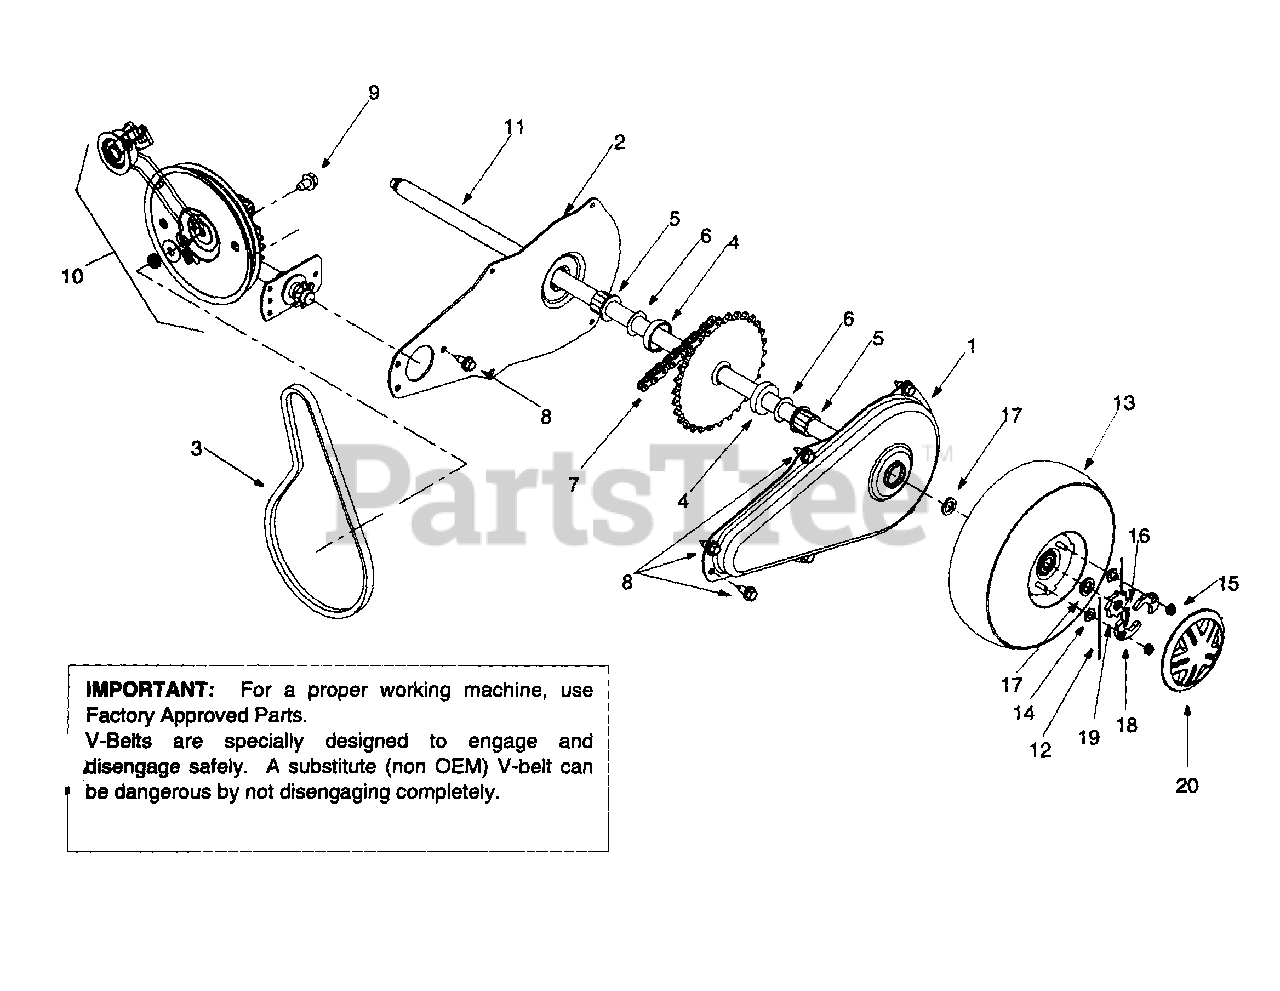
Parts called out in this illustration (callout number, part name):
3	V-Belt
4	Spacer
5	Hex Flange Bearing
6	Flat Washer
7	Chain
8	Hex Washer Screw 1/4-14
9	Hex Washer Screw 5/16
10	Transmission Asm
11	Axle Asm
12	Plastic Spring Ratchet
14	Hex Nut 1/4-20
15	Hex Flanged Lock Nut 1/4-20
16	Cotter Pin
17	Flat Washer 5/8 ID x 1.0 OD
18	Pawl LH .345 ID
19	Wheel Ratchet 1.62 OD x .5 serr
20	Hubcap
